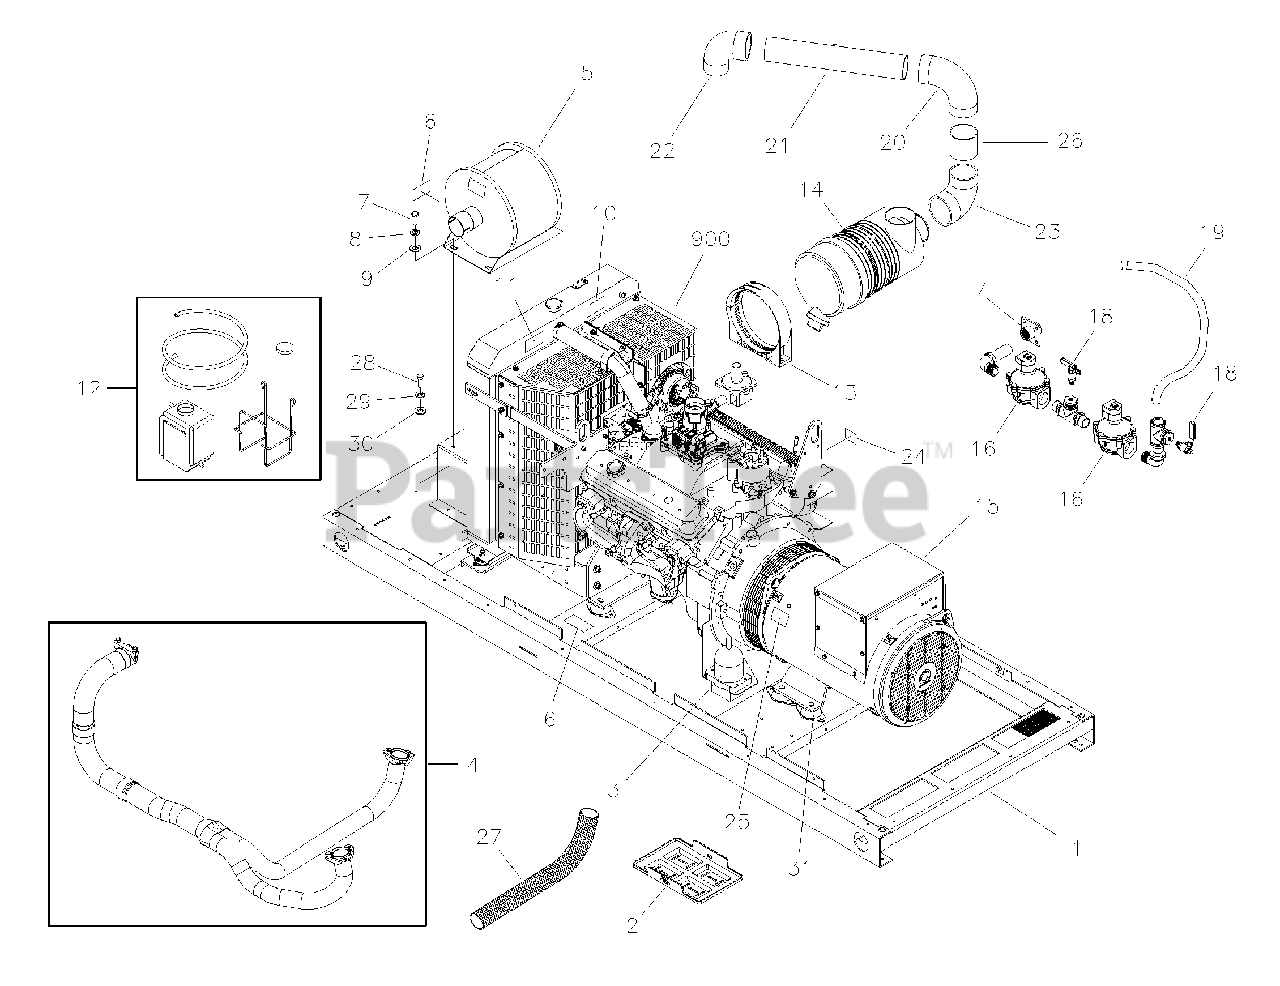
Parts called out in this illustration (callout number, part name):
1	BASE
3	ASSEMBLY, Heater, Tank
5	SILENCER, Muffler
6	DECAL, Burn Hazard
7	* CAPSCREW, Hex Head, 5/16-18 x 1
8	* WASHER, Lock, 5/16 - M8
9	* WASHER, Flat, 5/16 - M8
10	DECAL, Warning Hot Coolant
11	DECAL, Warning Moving Parts
12	KIT, Bottle Overflow
13	CLAMP, Air Cleaner
15	ASSEMBLY, Alternator
16	ASSEMBLY, Fuel Valve
17	COUPLER, Fuel System
18	VALVE, Ball 1/4
19	ASSEMBLY, Hose, Fuel
21	TUBE, Inlet, Air
24	DECAL, Oil Drain
25	DECAL, Explosion Hazard
26	TUBE, Inlet, Air
27	SLEEVE, Insulation
28	* CAPSCREW, Hex Head, 1/4-20 x 3/4
29	* WASHER, Lock, 1/4 - M6
30	* WASHER, 1/4
31	MOUNT, Vibration
900	** ENGINE
